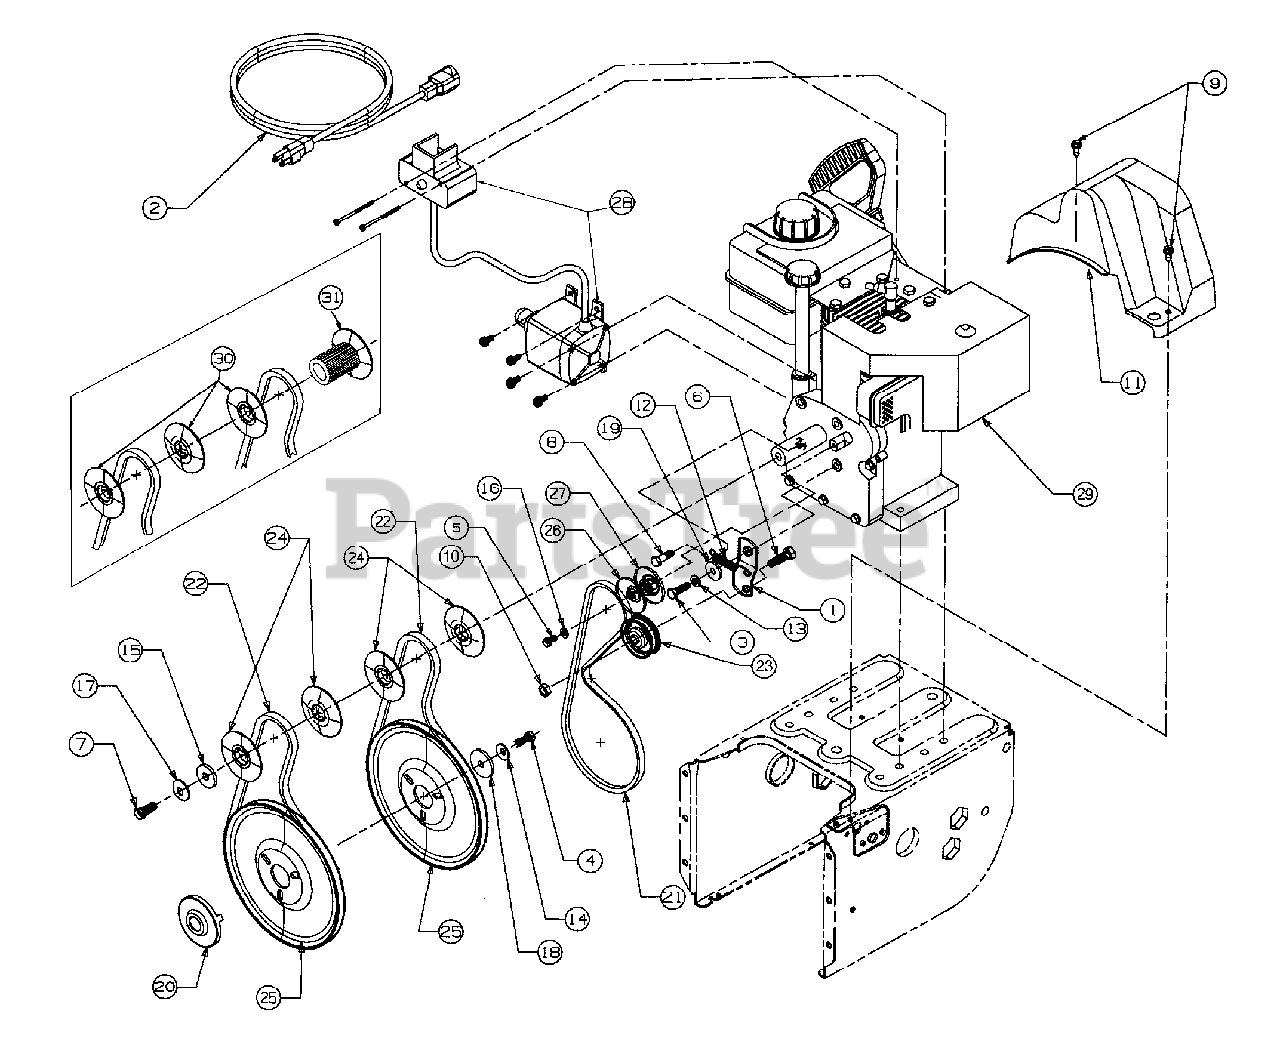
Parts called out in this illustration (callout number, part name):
3	Screw
4	Screw
5	Screw
6	Screw
7	Screw
8	Screw
9	Screw
10	Nut, Hex
11	Belt Cover
12	Spring
13	Washer - Flat
14	Washer - Bell
15	Washer - Flat
16	Washer - Lock
17	Washer - Bell
18	Washer - Flat
19	Shoulder Spacer
20	Pulley, Adapter
21	V-Belt
22	V-Belt Matched
23	Idler, Flat
24	Pulley, Half
25	Pulley - Auger
26	Pulley Half
27	Pulley Half
28	Starter (633)
29	Engine
30	Pulley, Half (633)
31	Pulley, Half (633)
